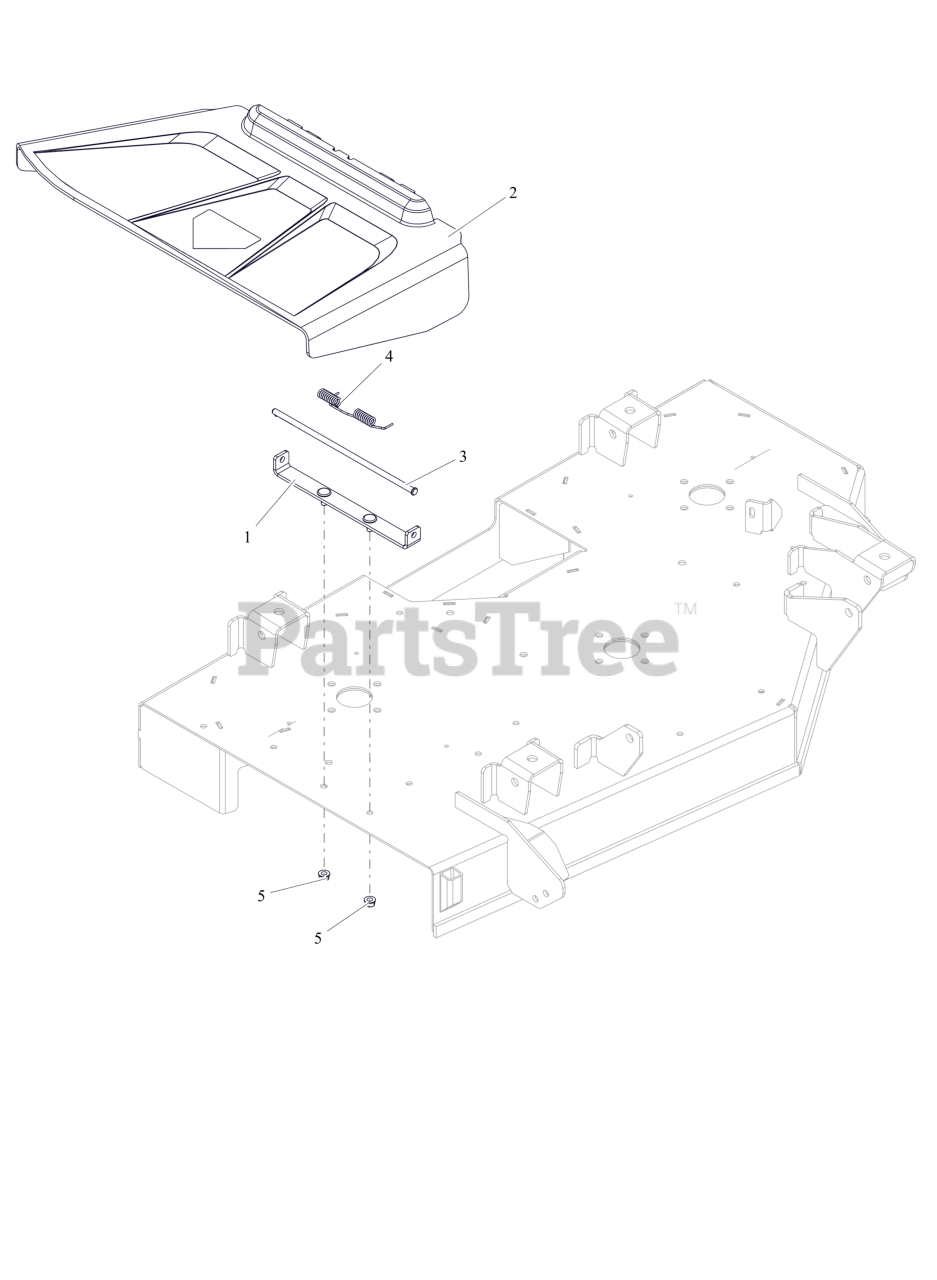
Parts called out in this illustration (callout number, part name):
2	CHUTE, SIDE DISCHARGE
3	PIN, SLIC-.312X10.45
4	SPRING-TORSION
5	NUT-LK-TOP-FLG .312-18 GF ZCC
